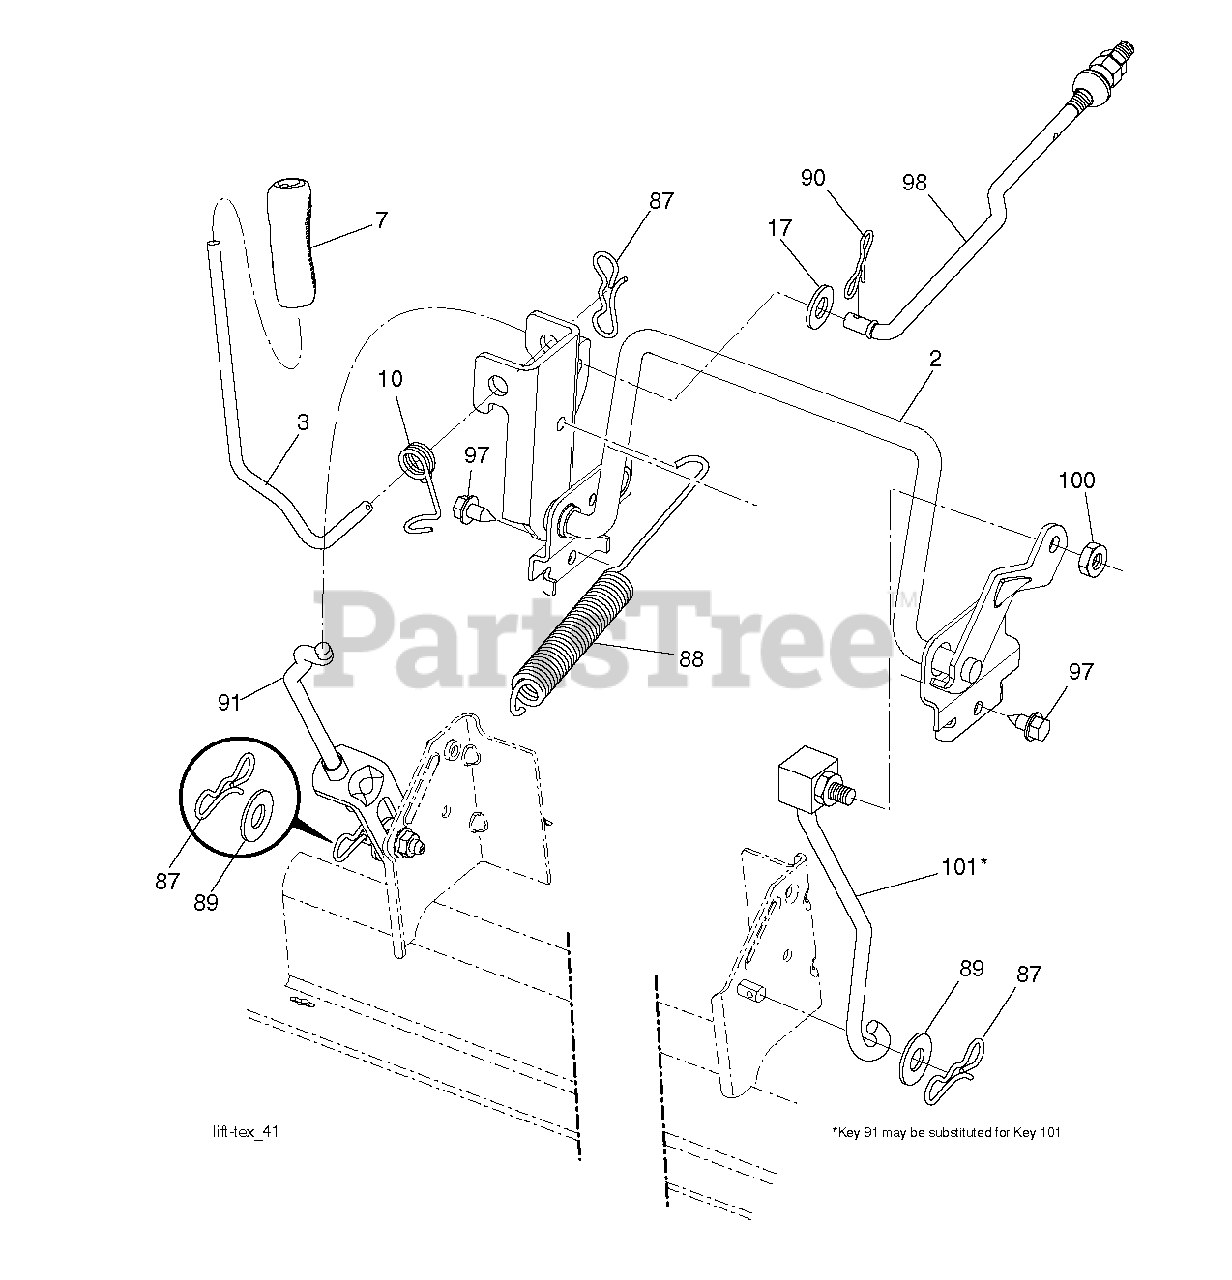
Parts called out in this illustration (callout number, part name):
2	SHAFT LIFT DECK WELD
3	LEVER.LIFT.HANDLE.LT
7	GRIP.HANDLE.LIFT.PVC.BLACK
10	SPRING.TORSION.LIFT.HANDLE
17	WASHER
87	PIN.COTTER.7/16.BOW TI.
88	SPRING.DK.LIFT.97/107.TXCRDII
89	WASHER.CLEAR.ZINC
90	PIN.COTTER.5/16.BOW TI
91	LINK.ASM.LIFT.REAR
98	LINK.ASM.SUSP.FRONT.MW
100	LOCKNUT
101	LINK.ASM.LIFT.FIXE.38/42/46"
